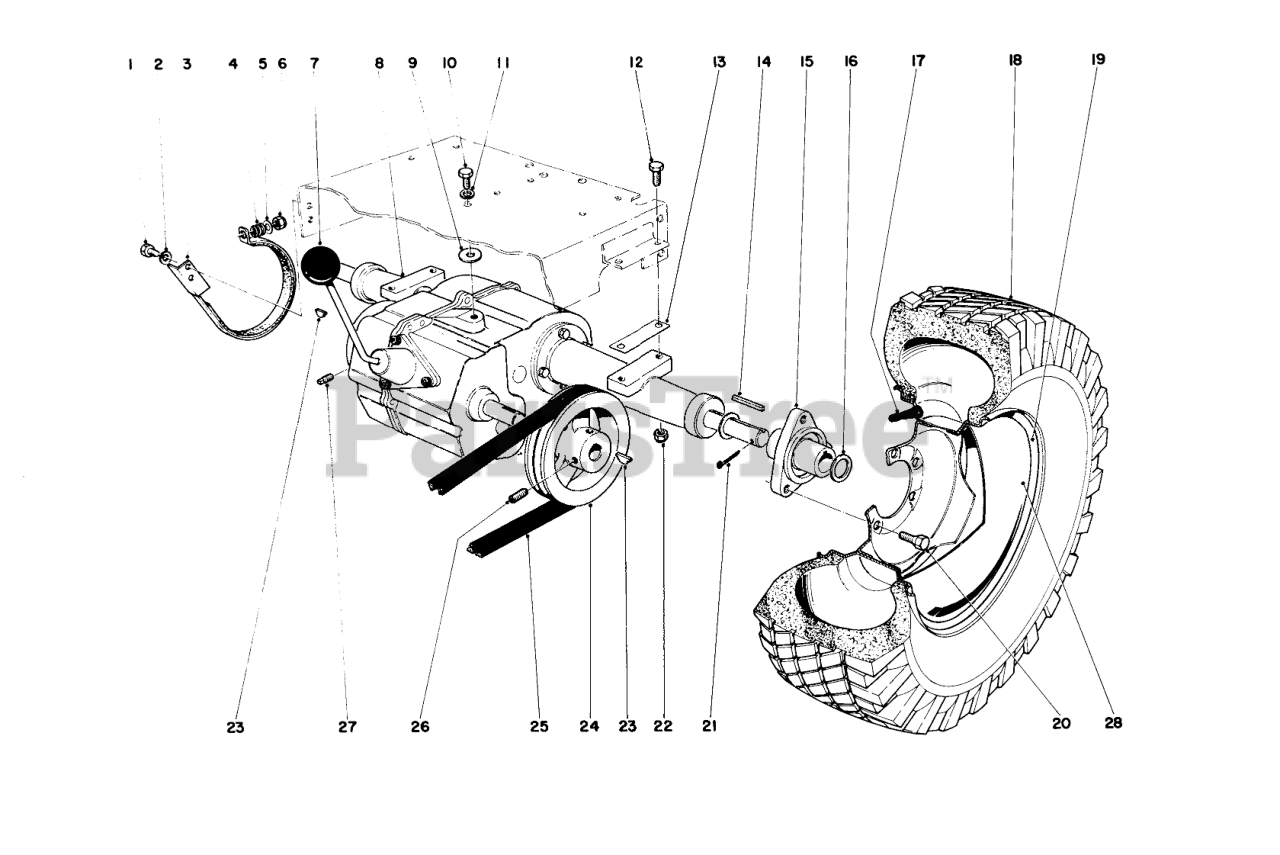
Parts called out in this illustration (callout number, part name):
1	SCREW-HH
2	WASHER-LOCK
3	Brake Band Assy.
4	Spring
5	WASHER-FLAT
6	NUT-LOCK, CONE
8	Transmission Complete
9	WASHER-FLAT
10	SCREW-HH
11	WASHER-LOCK
12	SCREW-HH
13	Axle Pad
14	KEY-SQUARE
15	Wheel Hub
16	Washer
17	STEM-VALVE
18	Tire
19	Rear Wheel
20	Tapered Capscrew
21	PIN-COTTER
22	NUT-LOCK, CONE
23	KEY-WOODRUFF
24	Pulley Transmission
25	V-BELT, TRANS (SET OF 2)
26	SCREW-SET
27	SCREW-SET
28	Hub Cap 960
